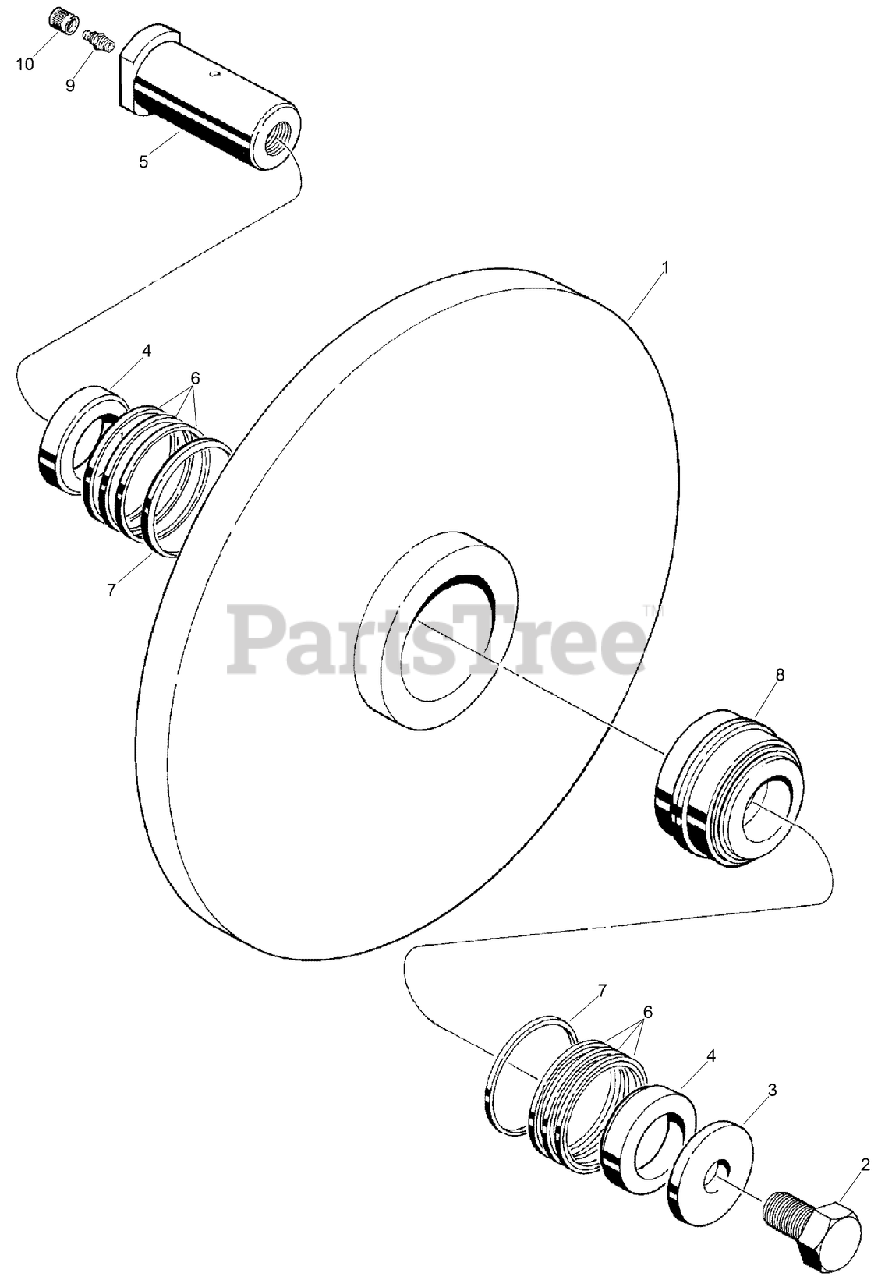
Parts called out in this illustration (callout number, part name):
1	ROLLER
2	BOLT - 3/4 x 1-1/2
4	SPACER-BEARING
6	SEAL-ROLLER
7	SPACER-SEAL, BOOM END
8	BEARING KIT
9	FITTING-LUBE, STRAIGHT
10	Cap
